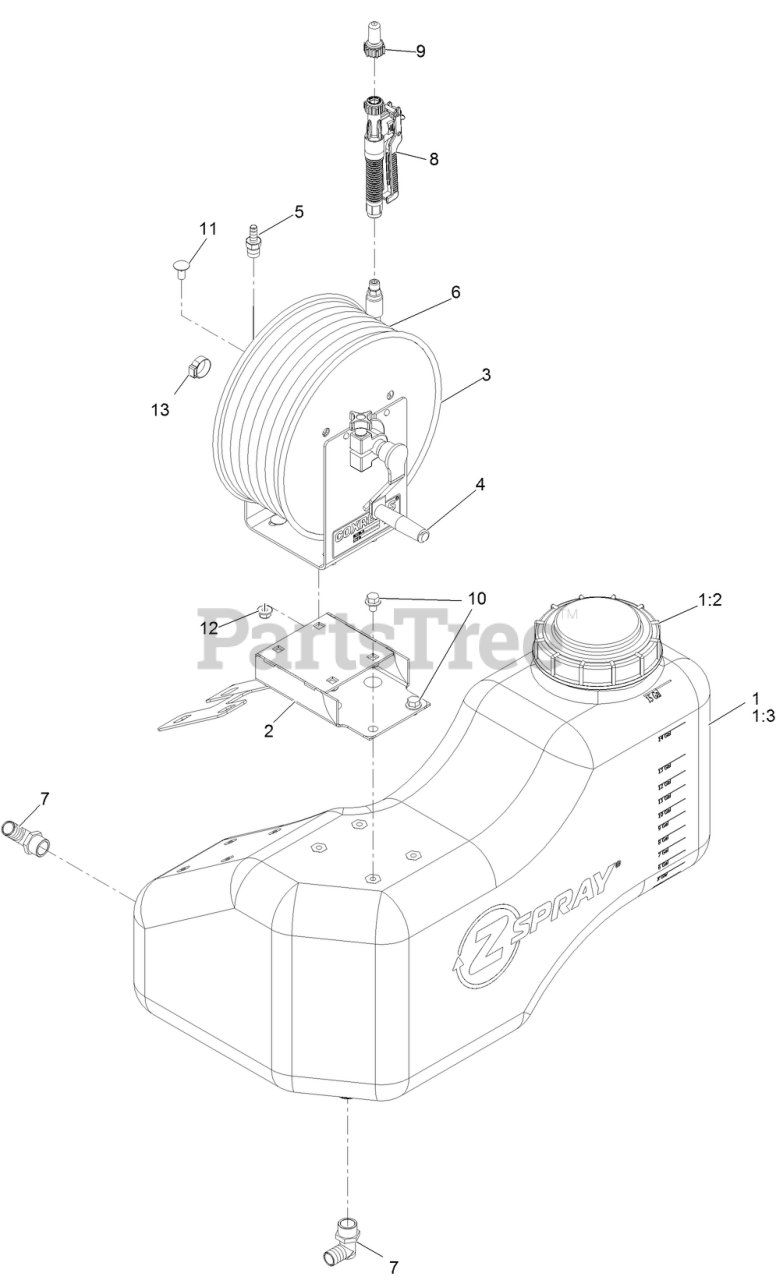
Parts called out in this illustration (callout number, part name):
1	ASM-TANK, LT
1:2	CAP-TANK, SPRAY
1:3	Fitting-Bulkhead
2	MOUNT-REEL, HOSE
3	REEL-HOSE
4	Crank-Reel
5	FITTING,MALE
6	HOSE-SPRAY, 75'
7	FITTING-ELBOW, 90
8	GUN-SPRAY, SPOT
9	TIP-SPRAY, #12 SPOT
10	Screw-HHF
11	SCREW-CARRIAGE
12	Nut-Hex Flange
13	CLAMP-OETIKER, 167
